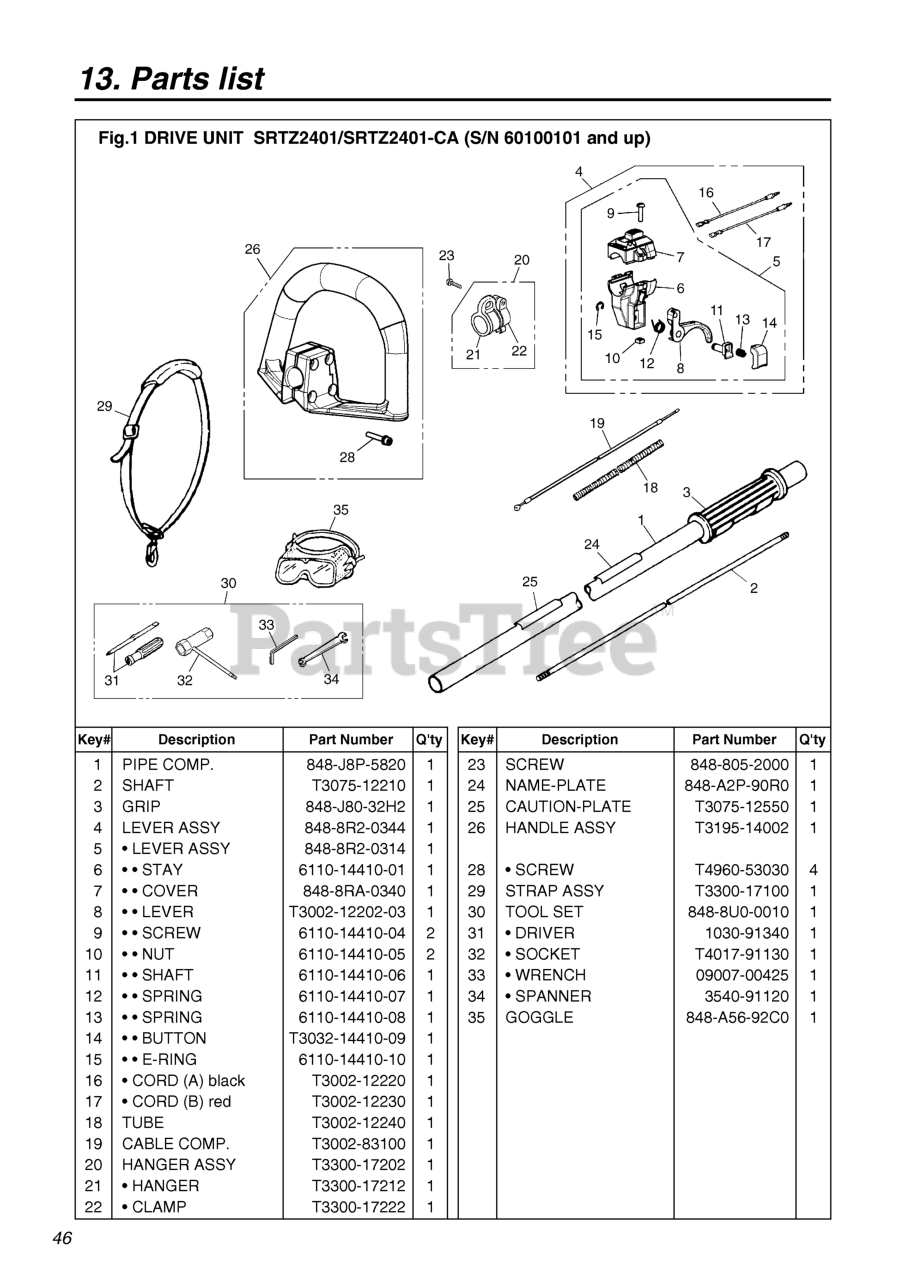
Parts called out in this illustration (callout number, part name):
1	PIPE COMP
2	SHAFT
3	GRIP
4	LEVER ASSY
5	LEVER ASSY
7	COVER
8	LEVER
16	CORD (A), BLACK
17	CORD (B), RED
18	TUBE
19	CABLE COMP
20	HANGER ASSY
23	SCREW
24	NAMEPLATE
25	CAUTION-PLATE
26	HANDLE ASSY
28	SCREW
29	STRAP ASSY.
30	TOOL-SET
31	DRIVER
34	SPANNER
35	GOGGLE
